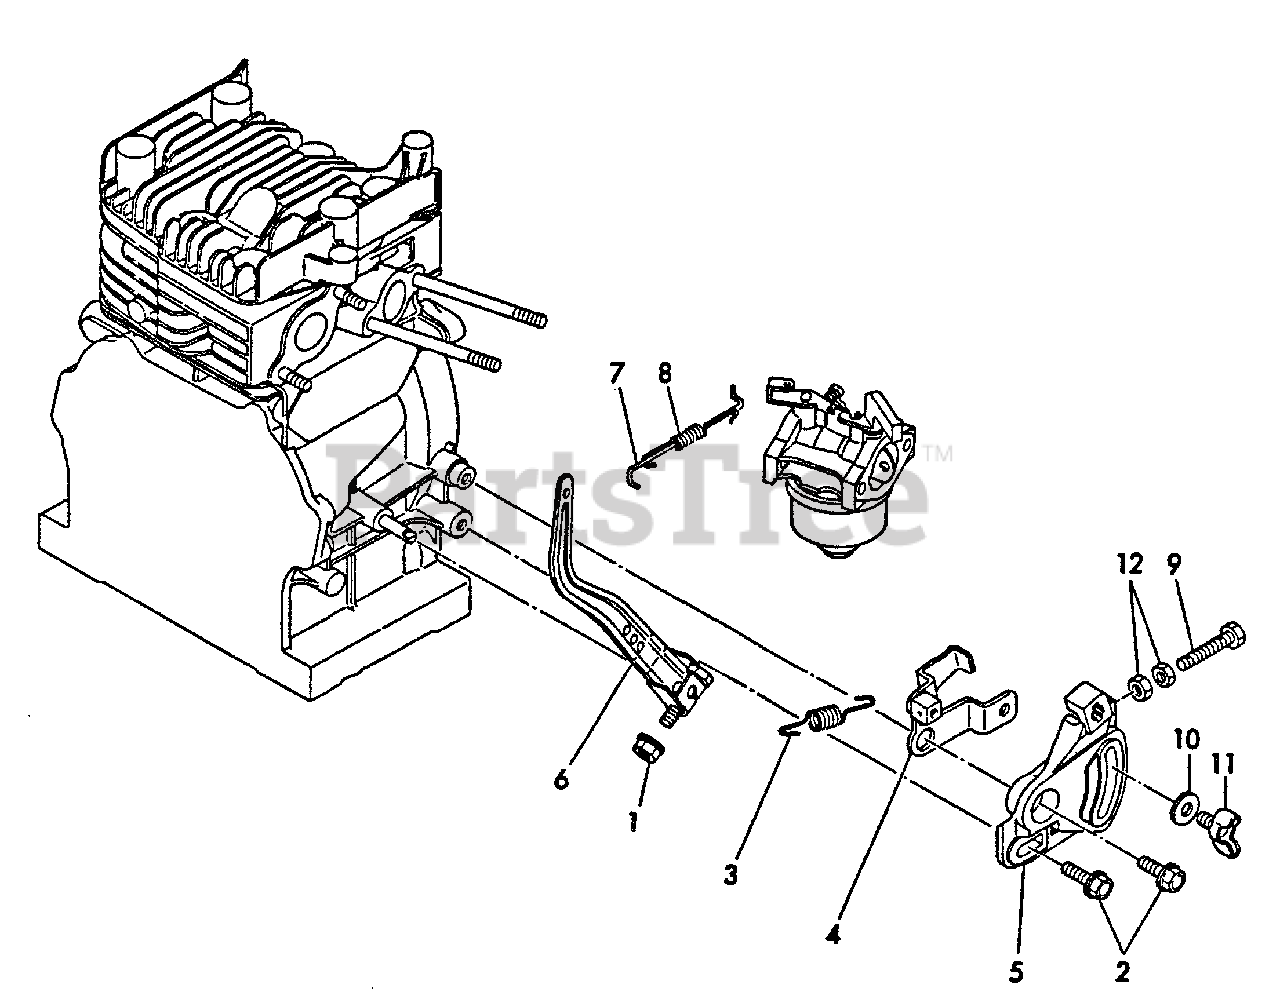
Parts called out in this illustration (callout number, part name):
1	NUT - 6 -- FLANGE
2	BOLT - 6X20
3	SPRING, REGULATOR
4	HANDLE, REGULATOR
5	BRACKET, REGULATOR
6	LEVER, GOVERNOR
7	LINK, THROTTLE
8	SPRING
9	BOLT
10	WASHER
11	THUMBSCREW
12	LOCKNUT - 6 -- PLATED
